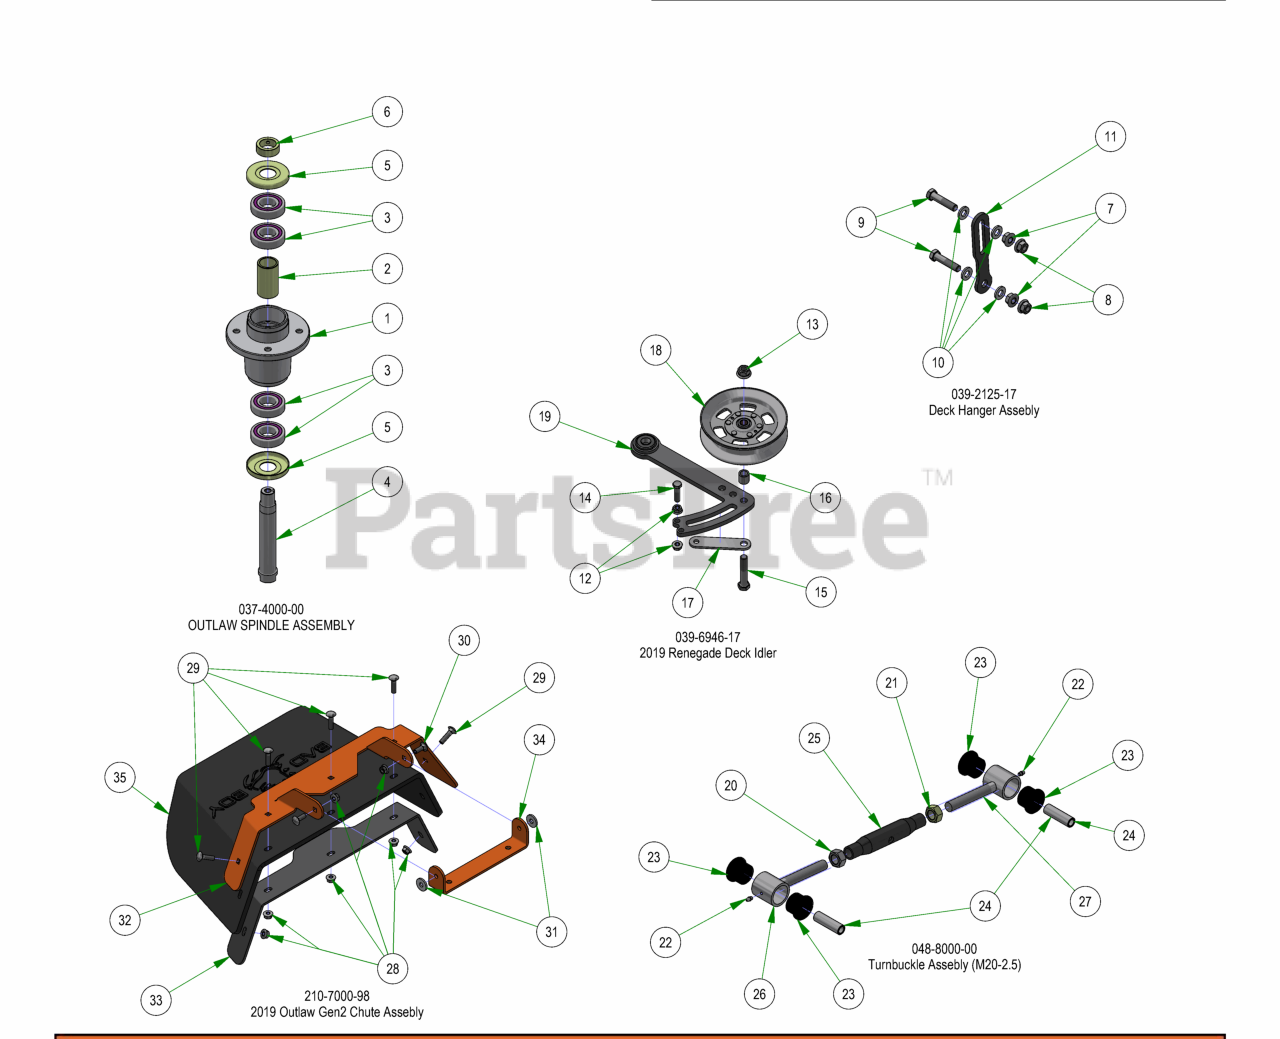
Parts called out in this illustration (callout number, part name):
1	4000 Series Spindle Housing
2	4000 Series Spindle Spacer
3	Bearing - 6206
4	Spindle Shaft
5	Spindle Dust Cap
6	Locking Collar w/ 1/4"-20 Set Screw
7	1/2-13 HEX SERRATED FLANGE NUT HARD/ZINC
8	1/2-13 NYLON INSERT FLANGE LOCKNUT ZINC
9	1/2-13 X 2-1/4 HEX CAP SCREW (GR.5) ZINC
10	.505 ID X 1.000 OD X .125 THICK FLAT WASHER NYLON
11	Deck Hangar
12	3/8-16 HEX SERRATED FLANGE NUT HARD/ZINC
13	1/2-13 NYLON INSERT FLANGE LOCKNUT ZINC
14	3/8-16 X 1-1/2 HEX CAP SCREW (GR.5) ZINC
15	1/2-13 X 2-3/4 HEX CAP SCREW (GR.5) ZINC
16	.51 ID X .75 OD X .75 LGTH SOLID SPACER ZINC
17	Belt Tensioner Retainer Plate
18	5" Idler Pully
19	2019 Deck Tensioner
20	Hex Nut M20-2.5
21	Hex Nut M20-2.5 Left Hand Threads Gold Plated
22	1/4-28 Grease Fitting
23	Polyeurethane Bushing
25	2024 Turnbuckle Body
26	Turnbuckle End Right-Handed Thread
27	Turnbuckle End Left-Handed Thread
28	5/16-18 NYLON INSERT FLANGE LOCKNUT ZINC
29	5/16-18 X 1-1/4 CARRIAGE BOLT ZINC
30	5/16-18 X 7/8 CARRIAGE BOLT ZINC
31	.360 ID X .983 OD X .120 THICK FLAT WASHER NYLON
32	2019 Upper Chute Bracket
33	2019 Lower Chute Bracket
34	2019 Chute Hanger
35	2019 Belted Chute with Logo
